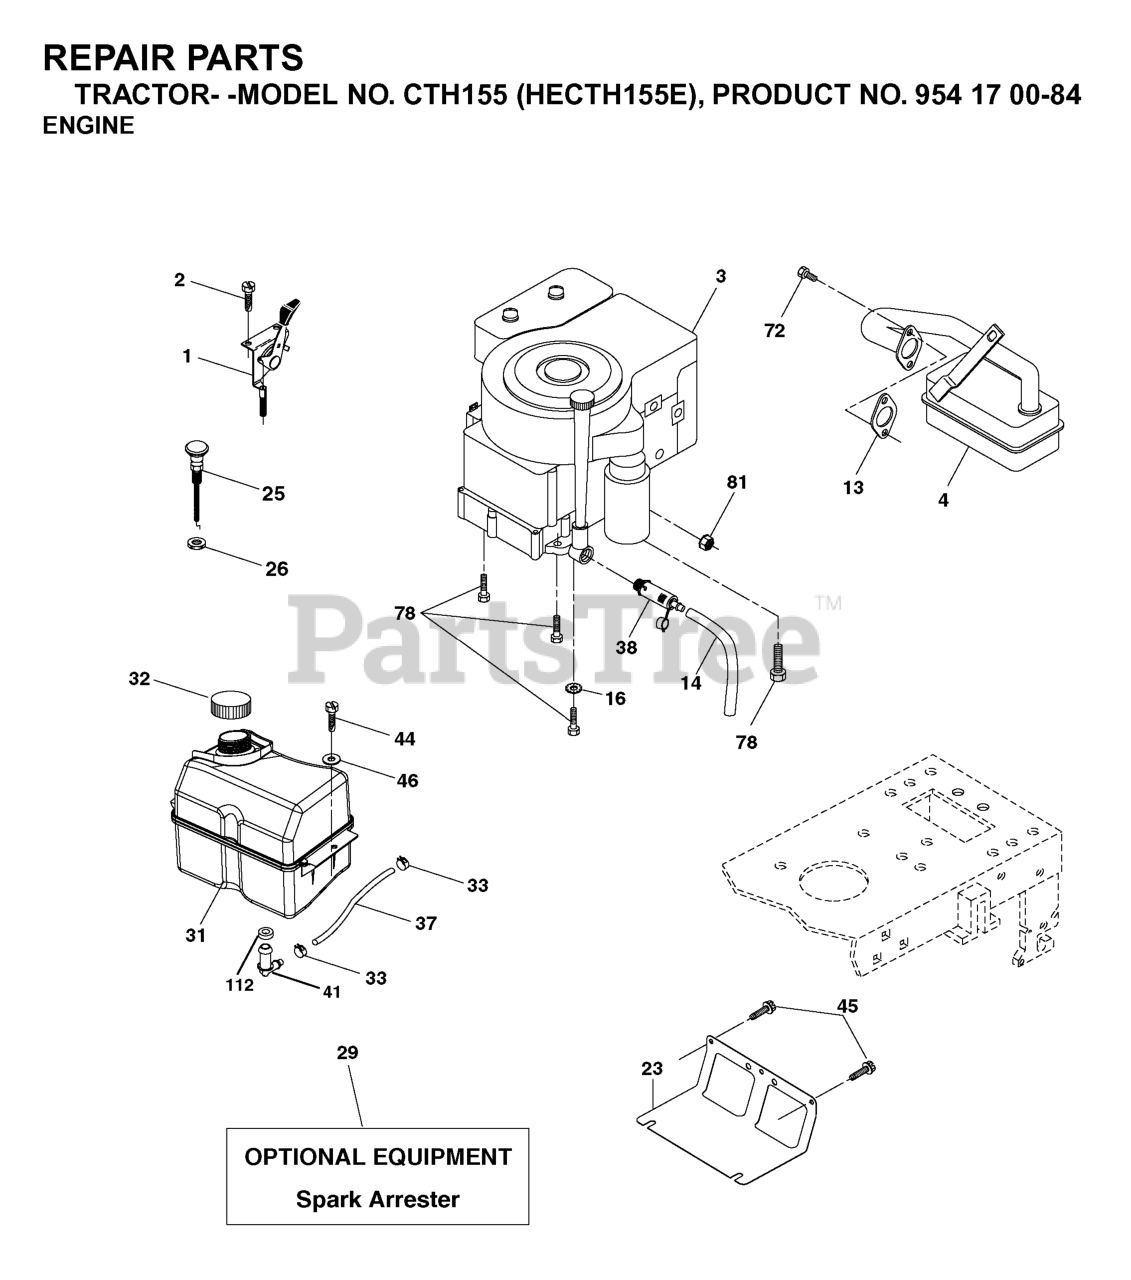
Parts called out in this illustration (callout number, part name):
1	CONTROL.THROTTLE/CHOKE.BLACK
2	SCREW
4	MUFFLER.LT.BRIGGS.14HP.IC/OHV
13	REPL BY 532 27 22-93
14	TUBE, DRAIN OIL ASM.
16	LOCKWASHER
23	SHIELD.BROWNING.DBR.GUARD
26	Nut Keps 3/8 - 24 UNF
29	KIT.SPARK ARRESTOR 794945 B&S
31	TANK FUEL
32	FUEL CAP
33	HOSE CLAMP
37	LINE.FUEL.20
38	PLUG DRAIN OIL EASY
41	STEM FUEL TANK
44	SCREW HEXWSHR 1/4-20X3/4
45	SCREW, 3/8-16X3/4
72	SCREW.SOCKET.HEAD.5/16-18
78	SCREW.3/8-16
81	NUT
112	BUSHING OUTLET T
